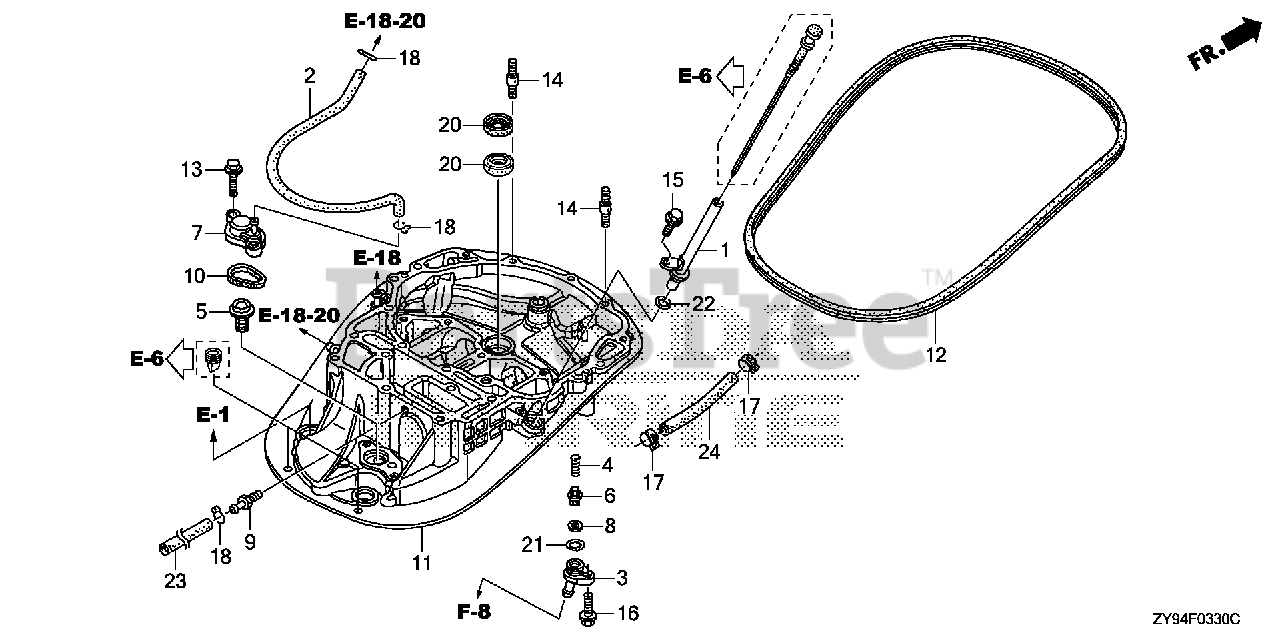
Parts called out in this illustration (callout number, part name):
1	PIPE, OIL LEVEL
2	TUBE B, WATER
3	COVER, FLUSH VALVE
4	SPRING, FLUSH VALVE
5	VALVE ASSY., RELIEF
6	VALVE, FLASH
7	COVER, RELIEF VALVE
8	GASKET, FLASH VALVE
9	JOINT, WATER TUBE
10	O-RING, THERMOSTAT COVER
11	CASE, MOUNT *NH8* (DARK GRAY)
12	SEAL A, COVER (LOWER)
13	BOLT, FLANGE (6X22)
14	BOLT, STUD (8X28)
15	BOLT, FLANGE (6X12)
16	BOLT, FLANGE (6X20)
17	CLAMP, TUBE (D10.5)
18	CLIP, TUBE (B10)
20	SEAL, WATER (22X35X7)
21	O-RING (16MM)
22	O-RING (11.5X3.5)
23	TUBE, WATER CHECK
24	BULK HOSE, VACUUM (7X3000) (7X110)
